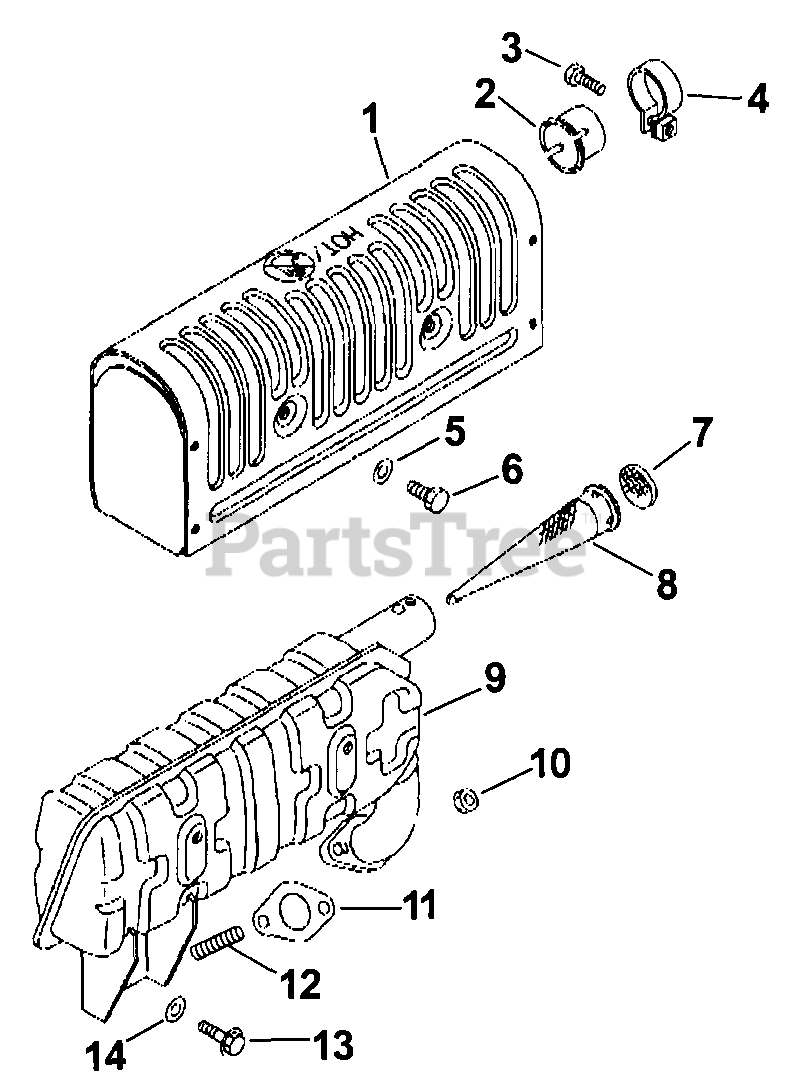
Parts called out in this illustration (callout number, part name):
2	CAP,MUFFLER
6	SCREW, HEX FLANGE
7	SCREEN, MUFFLER
8	SPARK ARRESTOR
10	NUT, EXHAUST
11	GASKET, EXHAUST
12	STUD, EXHAUST
13	SCREW, HEX FLANGE
